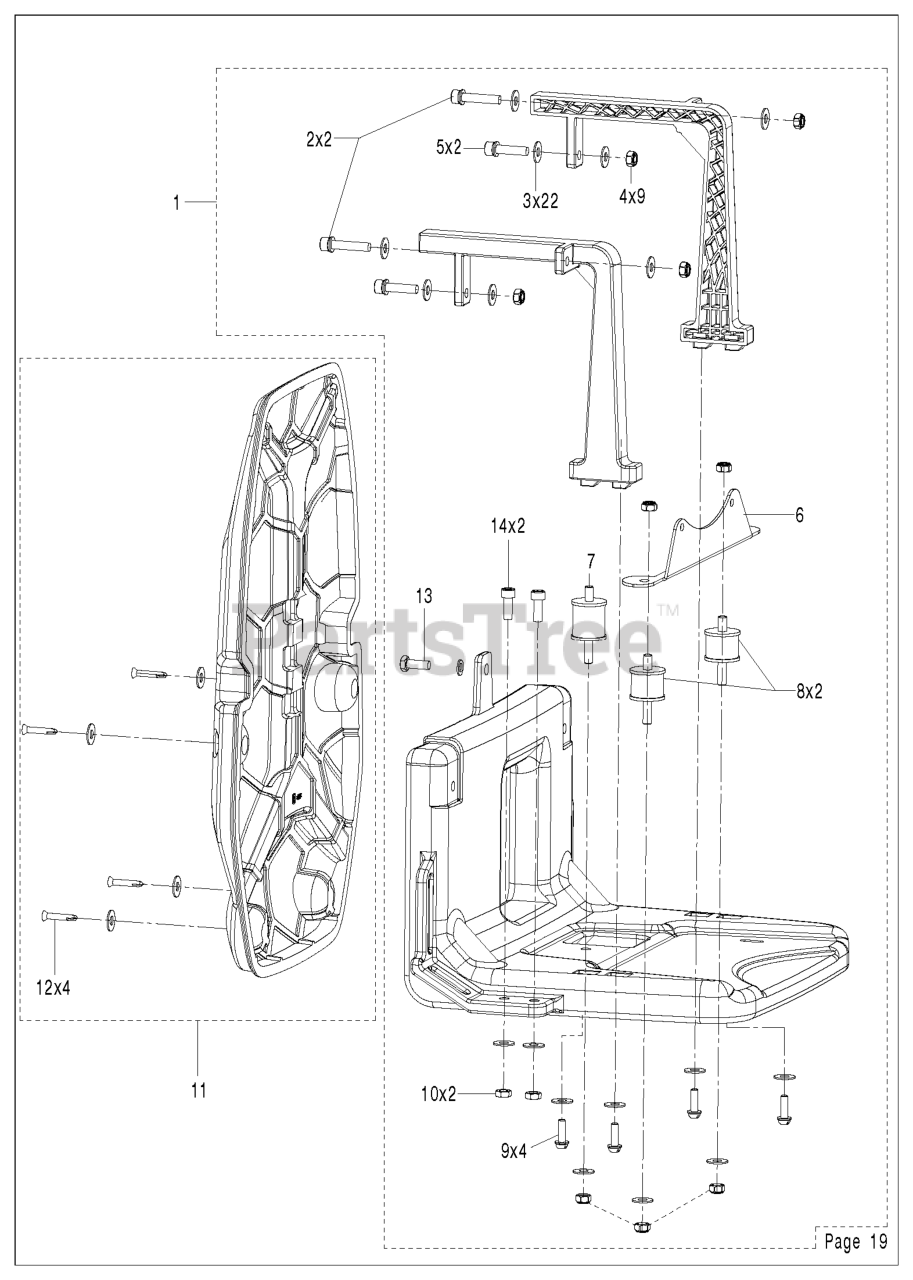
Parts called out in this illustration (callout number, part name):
2	MUFFLER.TWIN.CYL.LOW.TONE
9	KEEPER.BELT.ENGINE.4.2
11	CLUTCH.ELECTRIC.LT.48"*
12	PULLEY.ENGINE.TUFFTORQ
18	RP CAP FUEL
20	CONTROL.THROTTLE.PRO.
21	SCREW.#10 X 0.750.BOS
22	CONTROL.CHOKE.ERGO.PUSH-IN.BLA
28	LINE.FUEL.64"REAR.EMIS
29	KIT.SPARK ARRESTOR 794945 B&S
37	HOSE CLAMP
42	LOCKWASHER
45	NUT
62	SHIELD.HEAT.MUFFLER
69	GASKET.MUFF 806237 NOW 806425
70	EXHAUST.TUBE.MUFFLR.LH.VANG
71	EXHAUST.TUBE.MUFFLR.RH.VANG
79	SCREW.TUBE.MUFFLER.VANGUARD
81	TUBE, DRAIN OIL ASM.
82	VALUE.OIL.DRAIN
84	SCREW.3/8-16
85	BOLT HEX 7/16-20X4-1/4"
87	BOLT 5/1618UNC X 3/4 W/ SEMS
90	SCREW 3/8-16X1
91	BUSHING.1.375OD
116	RP KNOB SOFT TOUCH
117	VALVE FUEL RESERVE
